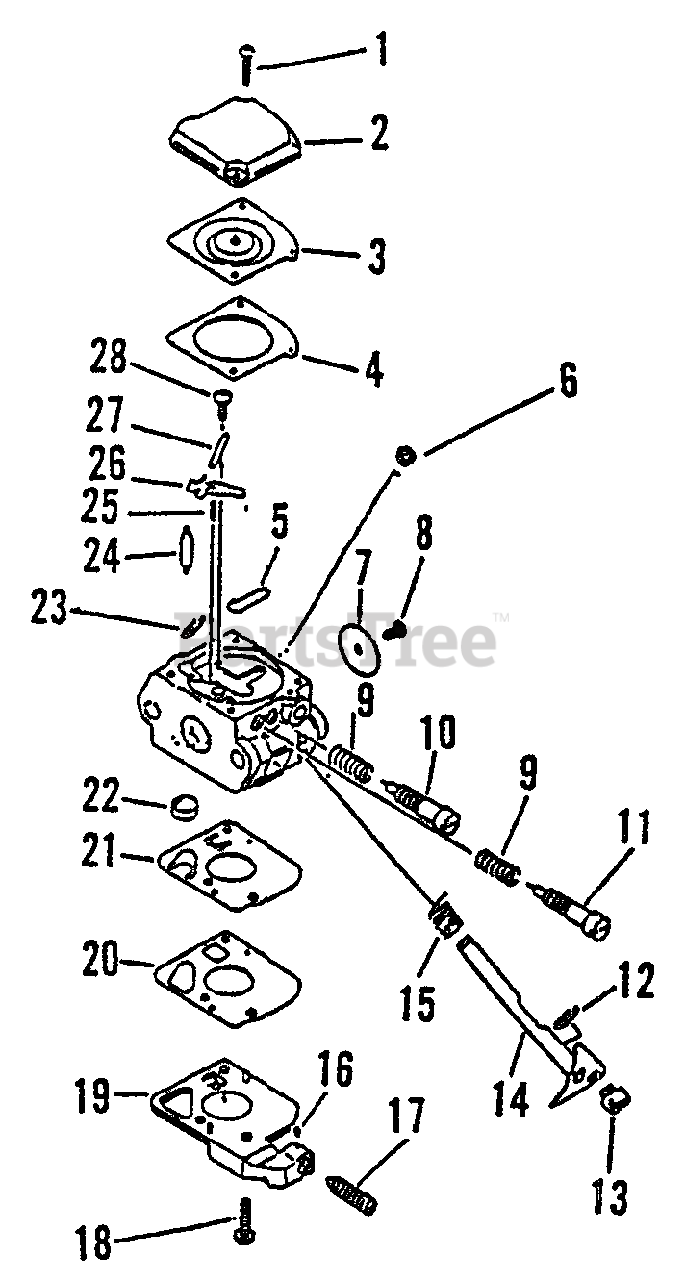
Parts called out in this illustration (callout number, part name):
1	CARBURETOR C1U-K9
2	COVER, METERING
3	DIAPHRAGM
4	GASKET, METERING
5	PLUG, WELCH
6	NOZZLE, CHECK VALVE
7	VALVE, THROTTLE
10	NEEDLE - HIGH SPEED
11	NEEDLE - LOW SPEED
12	RING, RETAINING
14	SHAFT, THROTTLE
15	SPRING, RETURN
16	PIECE, FRICTION
17	SCREW, IDLE ADJUST
18	SCREW, PUMP COVER
19	BASE, PURGE
20	GASKET, PURGE
21	DIAPHRAGM, PURGE
22	STRAINER
23	RING, RETAINING
24	VALVE, NEEDLE
25	SPRING
26	LEVER, METERING
27	PIN
28	SCREW, METERING LEVER PIN
